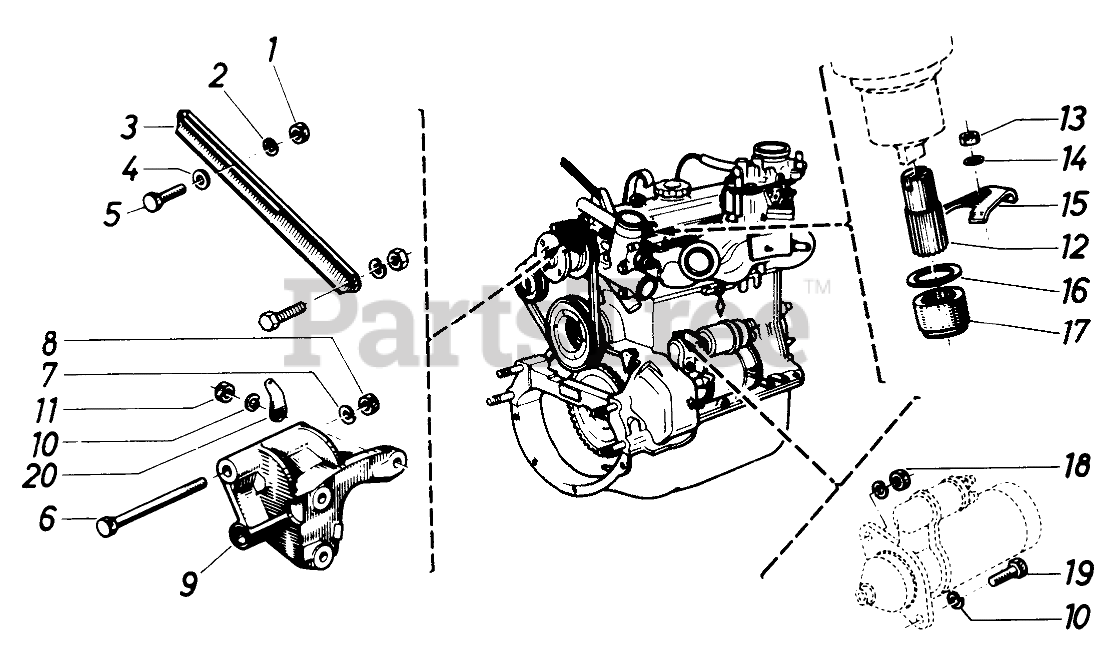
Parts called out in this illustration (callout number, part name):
2	Lockwasher
3	Tension Bracket
4	Washer
5	Screw
6	Screw
7	Spring Washer
9	Generator Bracket
10	Lock Washer
12	Splined Coupling
14	Washer
15	Bracket
16	Gasket
17	Support
20	Plate
